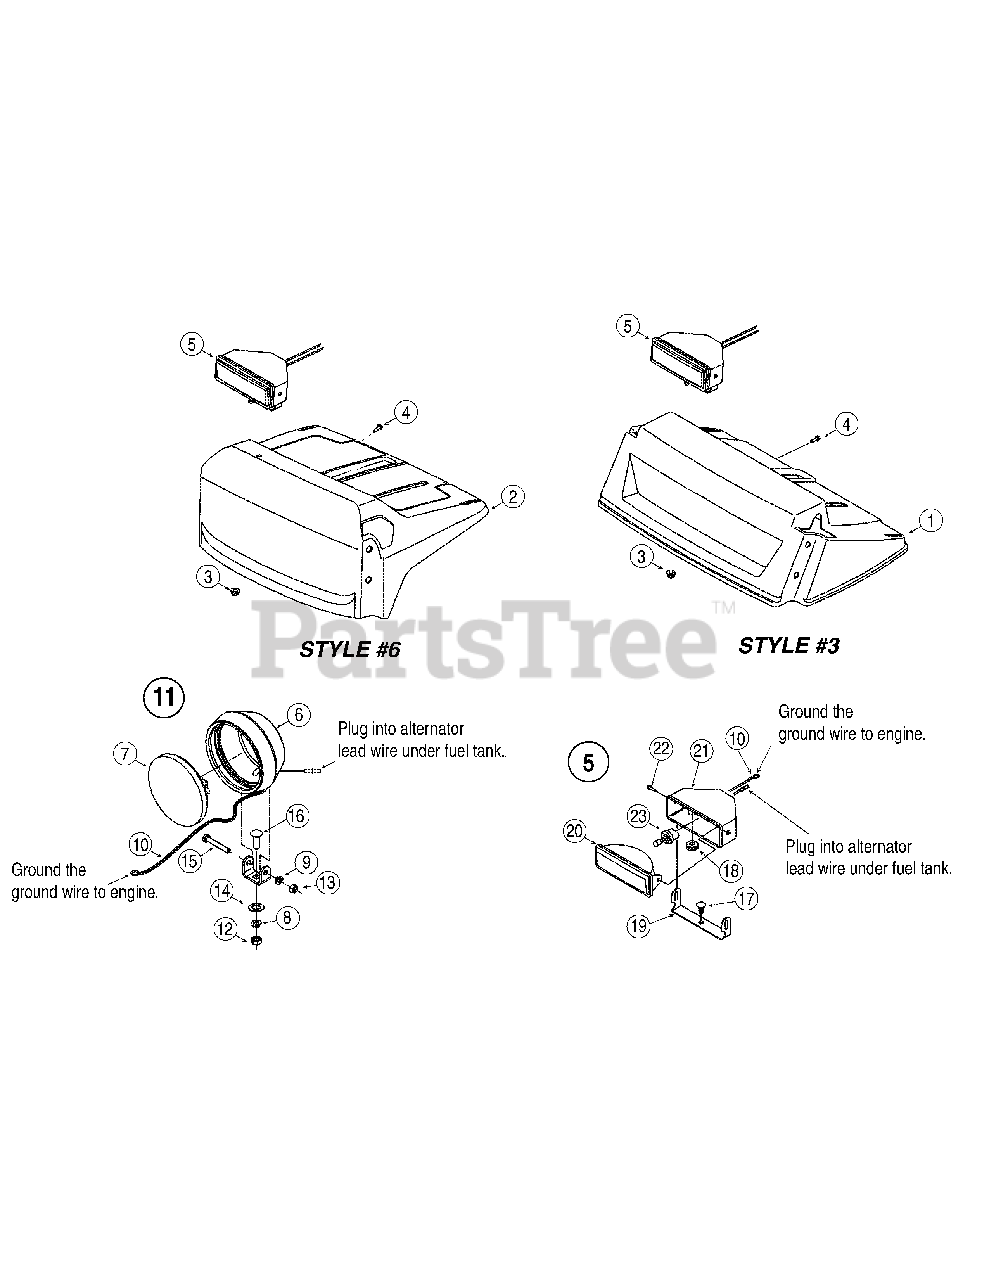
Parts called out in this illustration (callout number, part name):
1	Black Handle Panel
1	Yellow Handle Panel
1	Grey Handle Panel
2	Black Handle Panel
3	Hex Flange Locknut 5/16-18 Gr. F Nylon
4	Hex Tapp Wash Hd. Scr. #10 x 5/8
5	Top Mounting Halogen Lamp Assembly
6	Lamp Housing
7	Sealed Beam 18 Watt CGE #4414-1
8	L-Wash 5/16 ID
9	L-Wash 1/4 ID
10	Ground Wire
11	Top Mount 18 watt Lamp Ass’y (sealed beam)
12	Hex Nut 5/16-18 hd. Gr. 5
13	Hex Nut 1/4-28 Gr 5
14	Flat Wash .349 ID x .879 OD x .063
15	Hex Screw 1/4-28 x 1.75 Gr 5
16	Carriage Bolt 5/16-18 x 1.00" Lg
17	Carriage Bolt 5/16-18 x .75
18	Grommet .38 ID X .50 OD X .12
19	Lamp Mounting Brkt.
20	Lamp/Lens Housing Ass’y
21	Halogen Lamp Housing
22	Phillips Pan Hd. Scr. M4 x 16mm
23	Bulb #890, 12 V, 27 Watt
